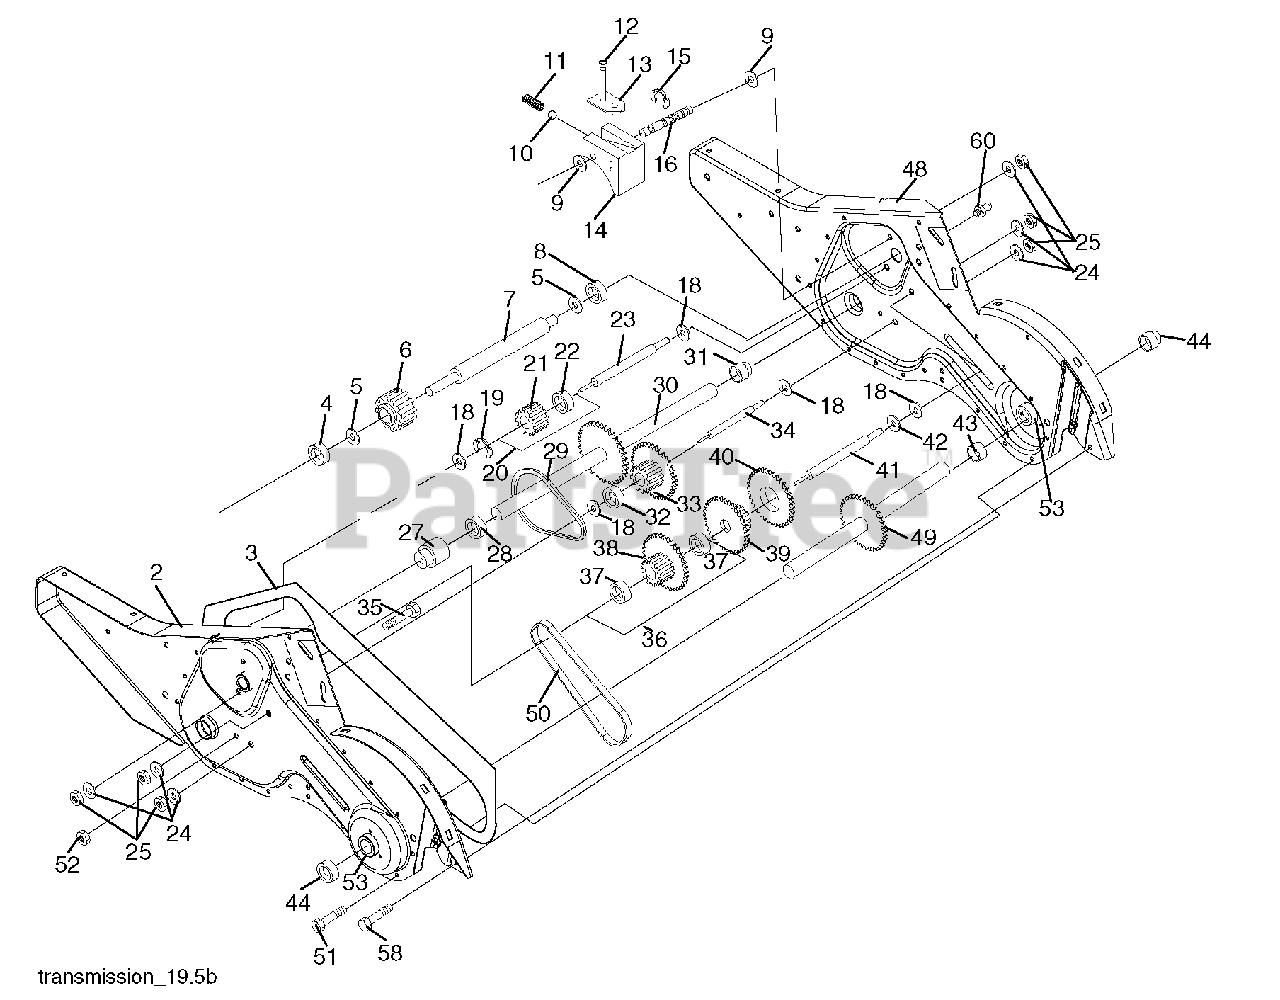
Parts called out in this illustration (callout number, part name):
1	Transmission Assembly
2	Gearcase, L.H. w/Bearing
3	Gasket, Gearcase
4	Bearing, Needle
5	Washer, Thrust 5/8 x 1.10 x 1/32
6	Pinion, Input
7	Shaft, In put
8	Bearing, Needle
9	Washer, Seal
10	Ball, Steel
11	Spring, Shift, Fork
12	O-Ring
13	Arm,. Shift
14	Fork, Shift
15	Ring, Klip
16	Shaft, Shift
18	Washer
19	Ring, Klip
20	Gear, As sem bly, Reverse Idler
21	Gear, Re verse Idler
22	Bearing, Needle
23	Shaft, Re verse Idler
24	Washer, Lock 7/16
25	Nut, Hex 7/16-20
27	Bearing, Shaft, Ground Drive
28	Spacer 0.765 x 1.125 x 1.23
29	Chain #35-50 Pitch
30	Ground Shaft Assembly
31	Bearing, Shaft, Ground Drive
32	Spacer 0.70 x 1.00 x 1.150
33	Sprocket and Gear Assembly
34	Shaft, Re duc tion (2nd)
35	Screw, Whiz, Lock 5/16-18 x 3-1/2
36	Sprocket Assembly w/Bearing
37	Bearing, Needle
38	Sprocket, Tine
39	Gear, Clus ter, Red 1st & 2nd
40	Gear, Re verse
41	Shaft, Re duc tion (1st)
42	Washer, Thrust
43	Spacer 1.01 x 1.75 x 0.760
44	Seal Asm, Oil
48	Gearcase, R.H. w/Bearing
49	Shaft, Tine
50	Chain, Roller #50-50 Pitch
51	Screw 1/4-20 x 1/2
52	Nut, Hex 5/16-18
53	Kit, Bearing, Tine Shaft
58	Bolt Shoulder 1/4-20 x 7/8
60	Fitting Grease
60	Grease, Plastilube #1
